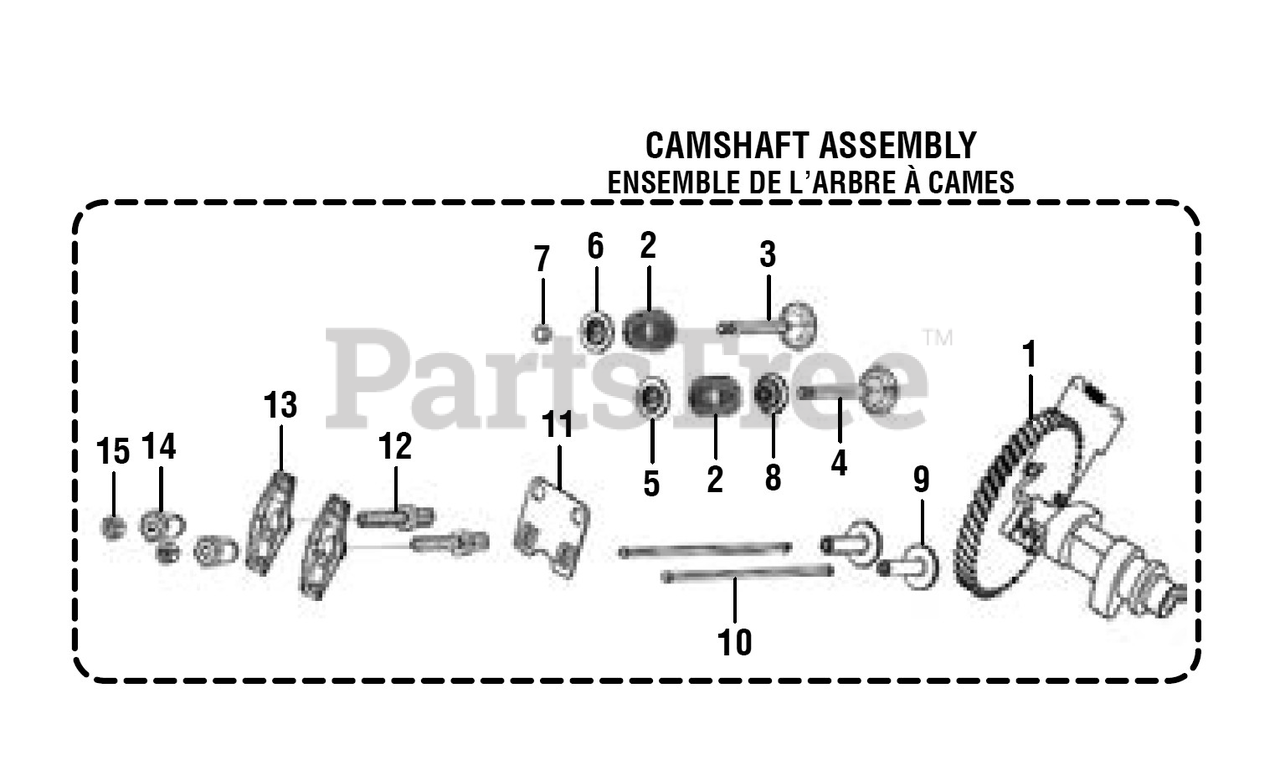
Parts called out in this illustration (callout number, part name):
1	Camshaft Assembly
2	Valve Spring
3	Exhaust Valve
4	Intake Valve
5	Valve Spring Seat
6	Retainer, Exhaust Valve
7	Valve Rotator
9	Valve Tappet
10	Valve Lifter
11	Lifter Stop Plate Assembly
12	Valve Adjusting Bolt
13	Valve Rocker
14	Valve Adjusting Nut
15	Valve Lock Nut
